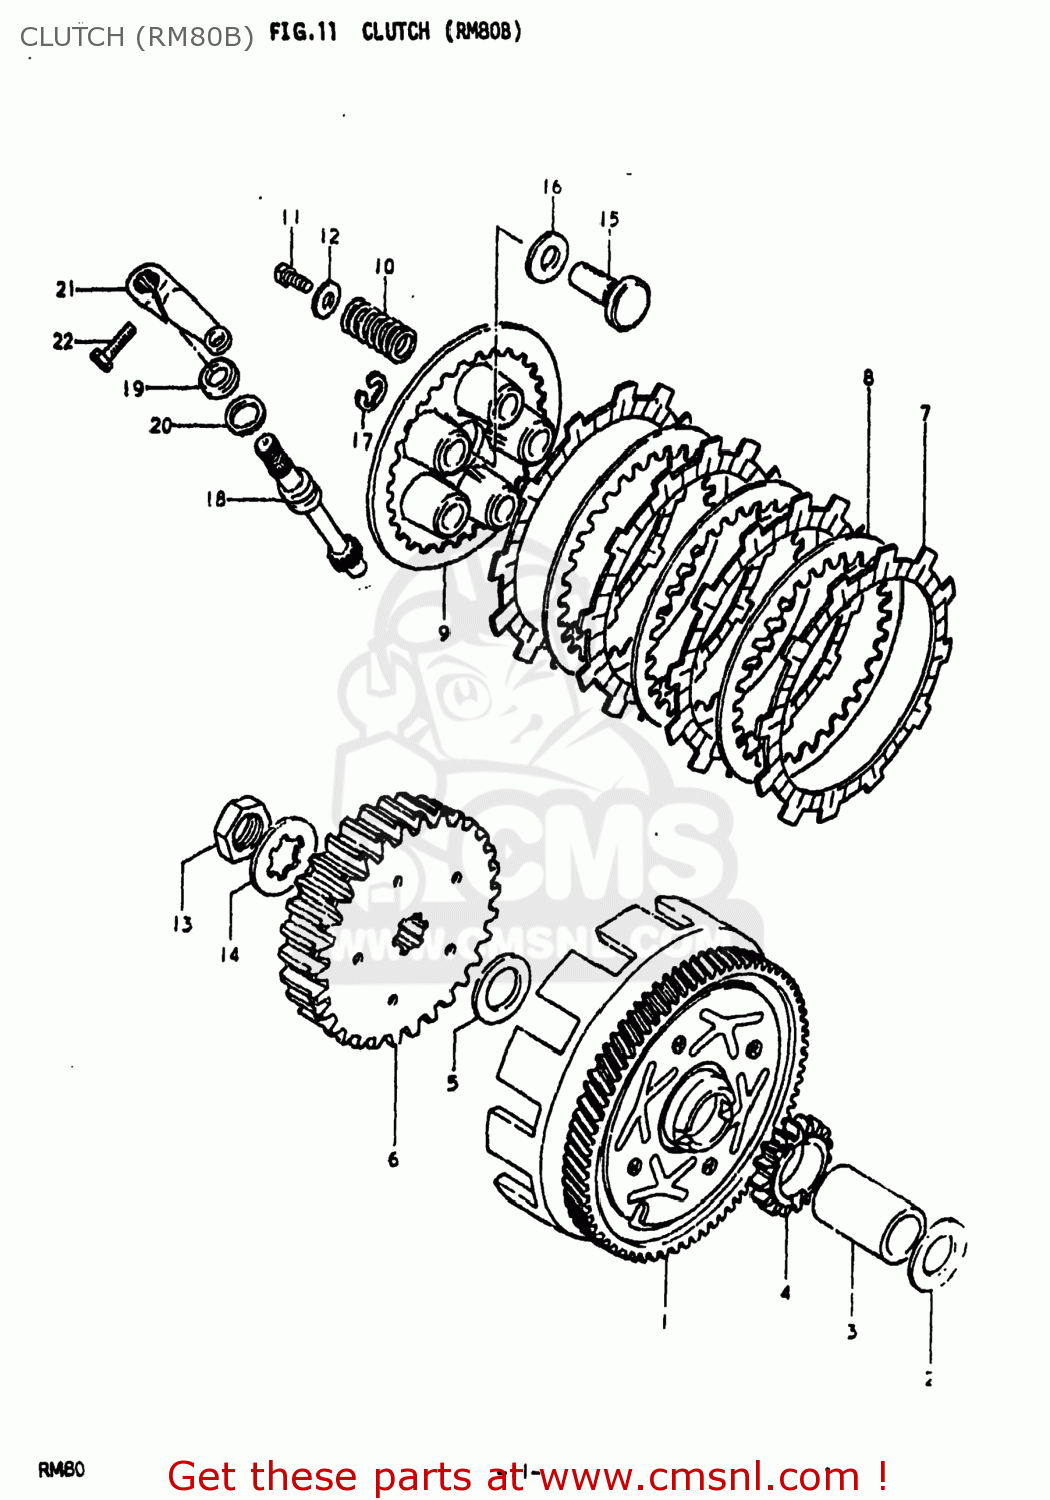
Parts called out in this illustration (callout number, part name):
1	GEAR ASSY,PRI DRIVEN(NT:73)
2	WASHER,THRUST
3	SPACER
4	GEAR,KICK STARTER DRIVE
5	WASHER
6	HUB,CLUTCH SLEEVE
7	PLATE,CLUTCH DRIVE
8	PLATE,CLUTCH DRIVEN (NAS)
9	DISC,CLUTCH PRESSURE
10	SPRING
11	BOLT
12	WASHER (5.5X16X1.2)
13	NUT
14	WASHER,LOCK
15	RACK,CLUTCH RELEASE
16	BEARING(10X22X2.8)
17	E RING 8MM
18	PINION,CLUTCH RELEASE
19	OIL SEAL
20	WASHER (12X17X1)
21	ARM,CLUTCH RELEASE
22	BOLT, UPPER
